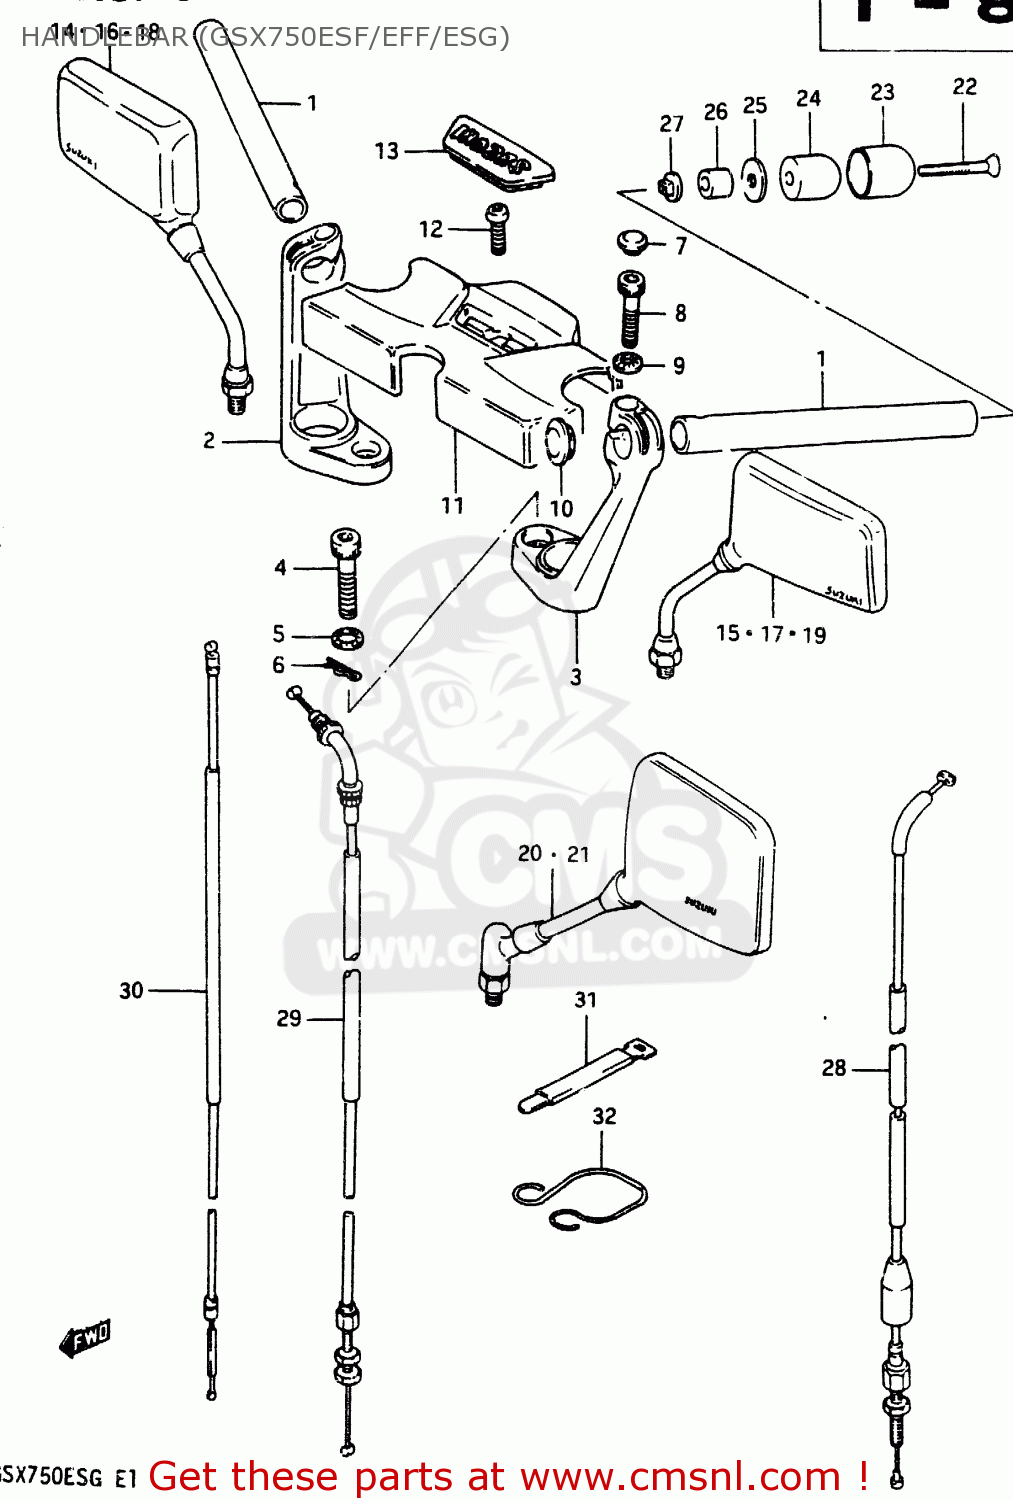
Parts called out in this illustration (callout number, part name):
1	HANDLEBAR
2	HOLDER,HANDLEBAR,RIGHT
3	HOLDER,HANDLEBAR,LEFT
4	BOLT 10X50
5	WASHER
6	CLIP
7	CAP(OD:14.5)
8	BOLT 8X35
9	WASHER
10	CAP,GRIP END
11	PAD,HANDLE
12	SCREW
13	CAP,HANDLE PAD
14	MIRROR ASSEMBLY,RIGHT
15	MIRROR ASSEMBLY,REAR VIEW
16	MIRROR, REAR VIEW RH
17	MIRROR, REAR VIEW LH
18	MIRROR, REAR VIEW RH
19	MIRROR, REAR VIEW LH
20	MIRROR ASSEMBLY,REAR VIEW
21	MIRROR ASSEMBLY,REAR VIEW
22	SCREW 6X65
23	CAP,BALANCER
24	BALANCER,HANDLE
25	SPACER,BALANCER
26	EXPANDER,BALANCER
27	NUT
28	CABLE ASSY,CLUTCH
29	CABLE ASSY,THROTTLE
30	CABLE COMP,STARTER
31	CLAMP
32	GUIDE,CABLE/HARNESS
